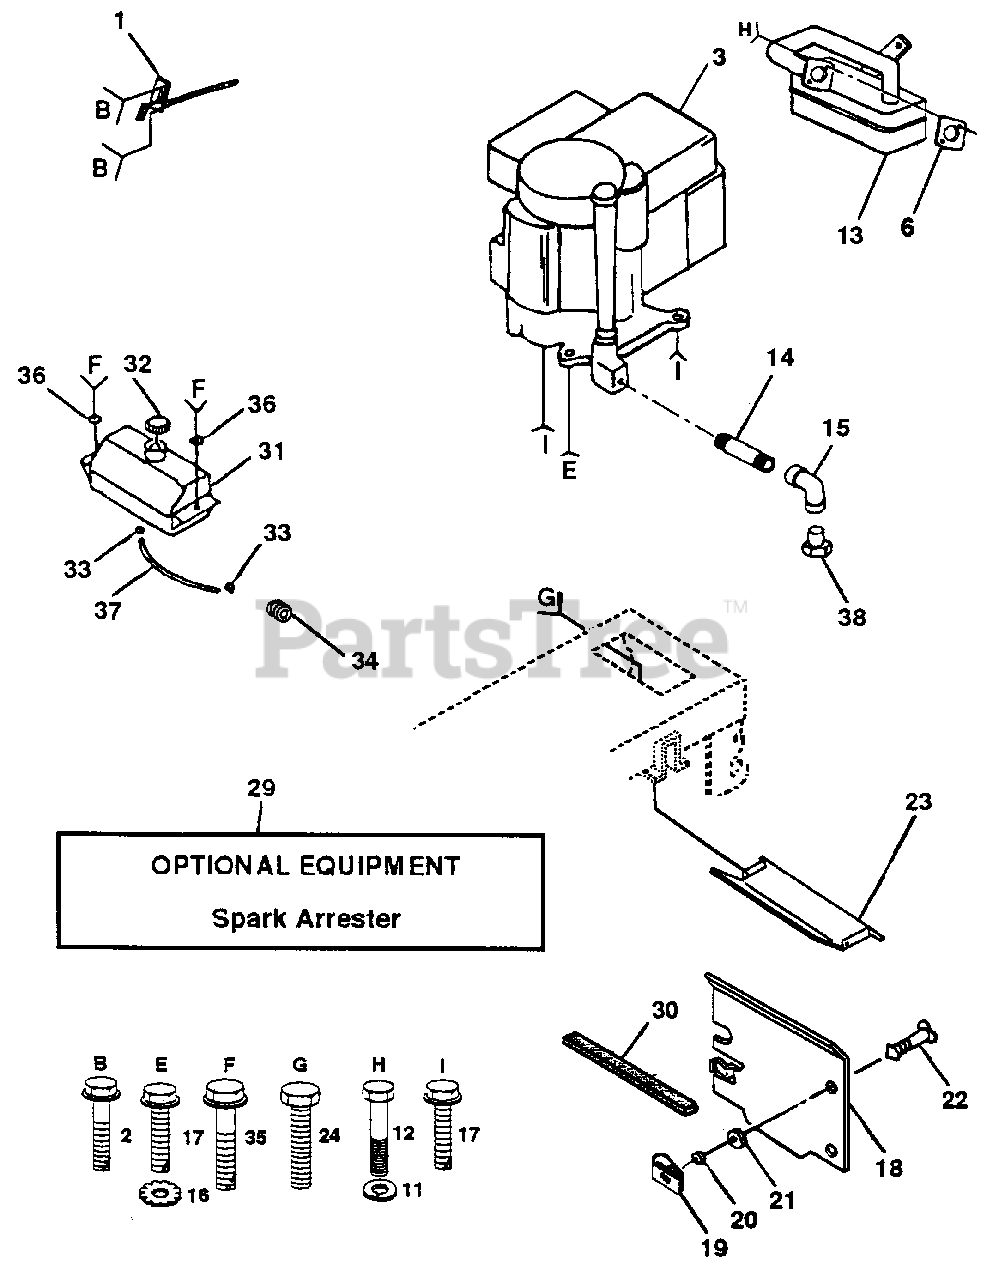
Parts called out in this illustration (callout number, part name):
1	Control Th/ch 23 5 LH Flag (AYP part number)
2	Screw Hex Thd Cut 1/4-20x5/8 T (AYP part number)
6	Gasket Eng 1 313 ld Tin Plated (AYP part number)
11	Washer Lock Hvy Hlcl Spr 5/16 (AYP part number)
12	Screw Hexhd Cap 5/16-18x 3/4 (AYP part number)
13	Muffler LT B&S 12/12.5/13HP (AYP part number)
14	Nipple Pipe 3/8 Npt X 3" (AYP part number)
15	Elbow Std 90 Degree 3/8-18 Npt (AYP part number)
16	Washer Lock Ext Tooth 3/8 (AYP part number)
17	Screw Thdrol 3/8-16x1-1/4 TYTT (AYP part number)
18	Shield Heat Lt (AYP part number)
19	Receptacle 1/4 turn (AYP part number)
20	Retainer 1/4 turn (AYP part number)
21	Washer 9/32 x 5/8 x 16 Ga. (AYP part number)
22	Stud 1/4 turn
23	Shield Heat Browning LT/YT (AYP part number)
24	Screw Tap Hex #10-24unc X 1/2 (AYP part number)
29	Kit Spark Arrestor (Flat Scrn) (AYP part number)
30	Pinch Weld Hood Black
31	Tank Fuel Front 2 00 (AYP part number)
32	Cap Asm Fuel W/sym Vented (AYP part number)
33	Clamp Hose Black (AYP part number)
34	Bushing Snap Nyl Blk Fuel Line
35	Screw Hexwsh Thdrol 1/4-20x3/4 (AYP part number)
36	Washer 9/32 X 7/8 X 16 Ga (AYP part number)
37	Line Fuel 20" (AYP part number)
